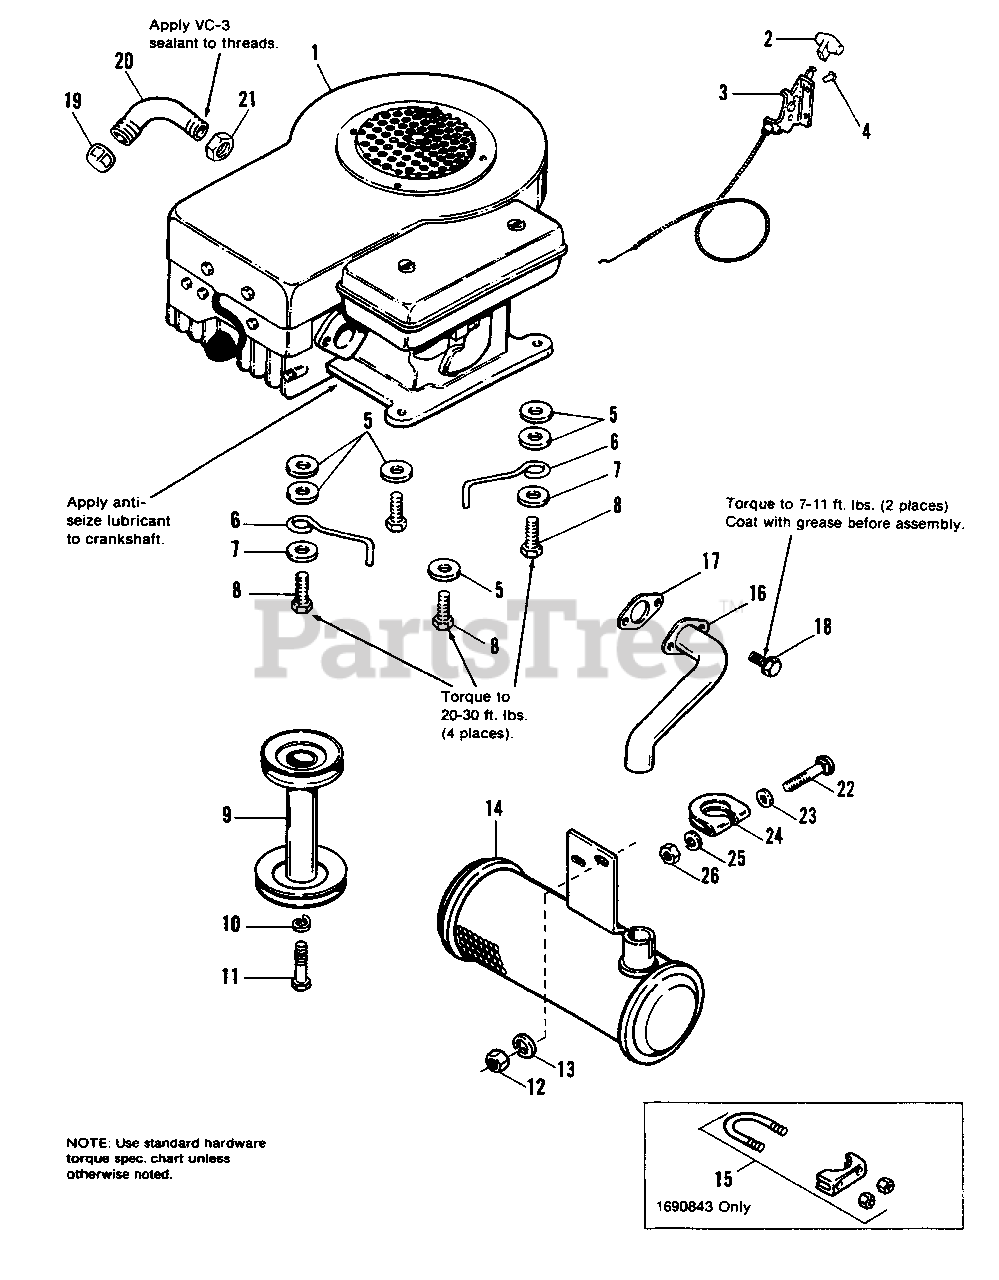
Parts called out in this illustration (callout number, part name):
1	ENGINE, 8 HP, Briggs & Stratton (1690840 only)
2	KNOB, Throttle
3	CONTROL ASSY., Throttle
4	RIVET, Pop, 1/4
5	WASHER, Plain, 3/8
7	WASHER, 3/8
8	SCREW, Taptite, 3/8-16 x 1-1/2
9	PULLEY ASSY., Engine
10	LOCKWASHER, 7/16
11	CAPSCREW, Hex, 7/16-20 x 1-1/4
12	NUT, Hex, 5/16-18 (1690843 & 1690909)
13	LOCKWASHER, 5/16 (1690843 only)
14	MUFFLER, (1690843 & 1690909)
15	CLAMP ASSY., Exhaust (1690843 only)
16	PIPE, Exhaust (1690843 & 1690909)
17	GASKET, Muffler (1690843 & 1690909)
18	SCREW. Whizlock, 5/16-18 x 3/4 (1690843 & 1690909)
20	PIPE, Oil Drain
21	LOCKNUT, Conduit (1690909 only)
22	BOLT, Carriage 5/16-18 x 3-2//4 Gr. 5 (1690909 only)
23	WASHER, 5/16 (1690909 only)
24	CLAMP (1690909 only)
25	LOCKWASHER, 5/16 (1690909 only)
26	NUT, Hex, 5/16-18 (1690909 only)
